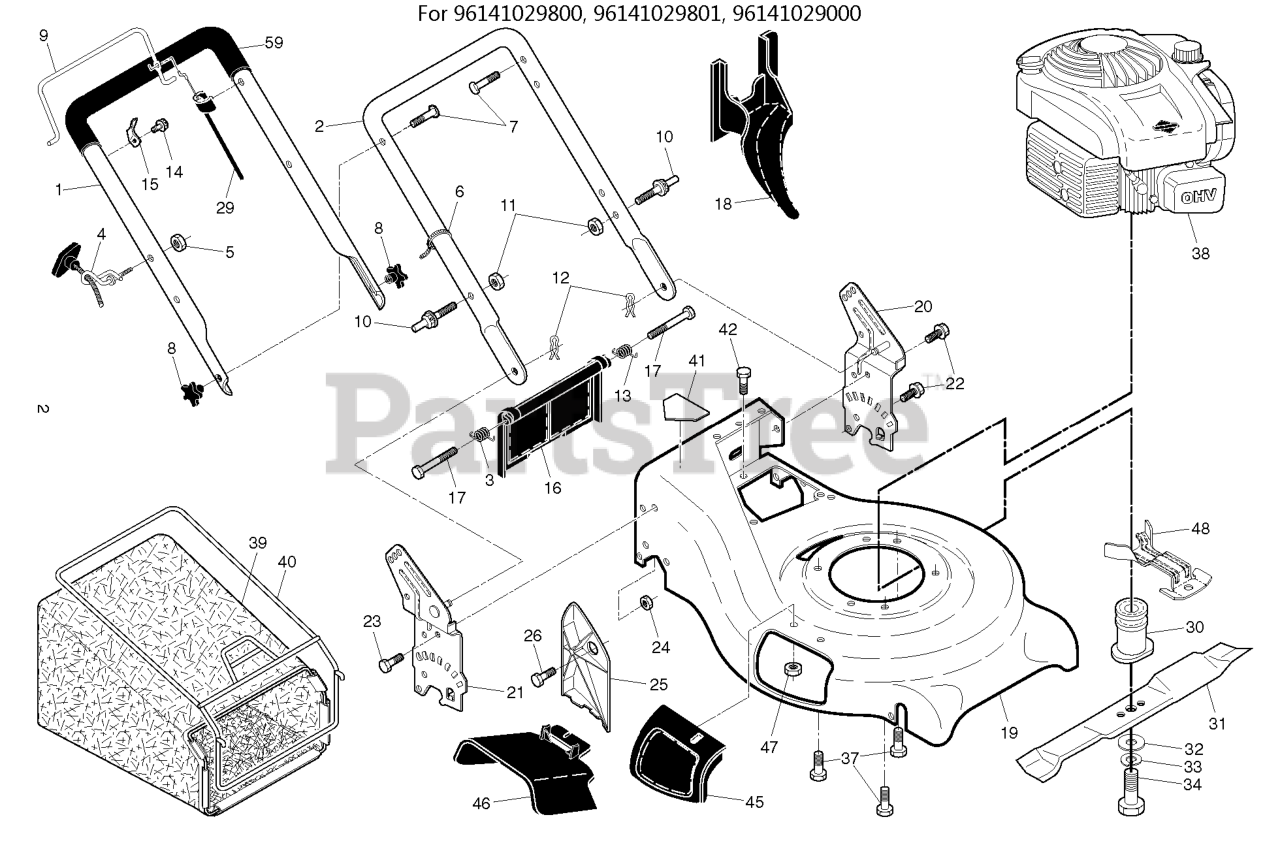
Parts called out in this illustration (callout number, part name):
1	HANDLE.ASM.UP.BS.PU/SS.GRP.GRE
1	HANDLE.ASM.UP.BS.PU/SS.GRP.498
2	HANDLE.LOWER.21.GREY
3	SPRING.RH.REAR.DOOR.21.RWGD
4	GUIDE.ROPE.BLK.ZINC.CHROM
5	T-KNOB.NEW ROPE GUIDE
6	TIE GUIDE
7	BOLT, HANDLE 5/16-18X1.75
8	KNOB.HANDLE.PLASTIC.STAR.BLACK
9	BAIL.CONTROL.MZR.BS.ORANGE
11	NUT.LOCK.5/16-18
12	HAIRPIN COTTER
13	SPRING.LH.REAR.DOOR.21.RWGD
15	BRACKET.UPSTOP.RT
16	DOOR.REAR.21.RWGD.498
18	PLUG.MULCHER.RGD.21.
19	KIT.HSG.21.RGD.MC.ORG.CE
20	BRACKET.HNDL.ASM.21.RWGD.LT.OR
21	BRACKET.HNDL.ASM.21.RWGD.RT.OR
22	BOLT.HEX.HD.WASHER.5/16-18X.75
23	BOLT, HEX HEAD 5/16-18
24	NUT.71038.31-18.HEX.NYLOCK
25	CLIPPING DEFLECTOR
29	CABLE.MZR.RGD.22.B&S/HON.ERGO
30	BLADE ADAPTER PULLEY
30	ADAPTER.BLADE/PULLEY.25M
31	BLADE.21.PUSH
32	WASHER,HARDEN
33	LOCKWASHER
34	SCREW, HEX HD 3/8-24 X 1-3/8
37	BOLT 3/8-16X1-1/8
39	GBAG.94710090.H-GRY.MS498.GEN
40	FRAME.GBAG.21.RWGD.SC
41	DECAL.INTERNATIONL.CUTFINGER
42	SCREW 14-20 X 5/8
45	MULCHER DOOR ASM.
46	DEFLECTOR, DISCHARGE
48	BRACKET.ENG/BELTKEEPER.BZP
59	GRIP, FOAM
